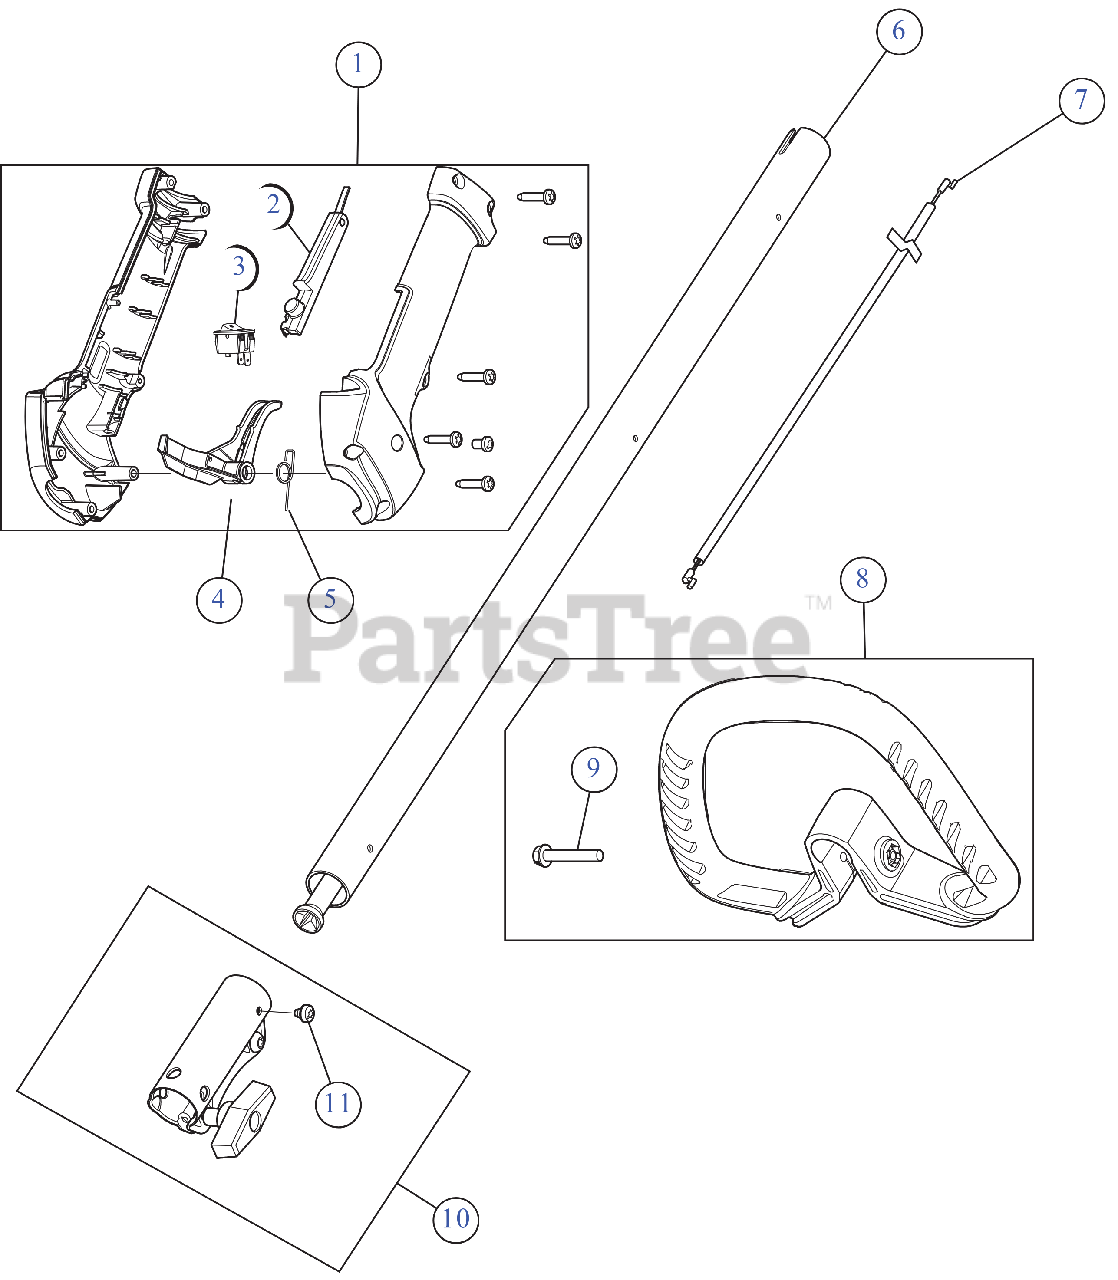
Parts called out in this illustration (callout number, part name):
1	THROTTLE GRIP ASSEMBLY
2	LEVER LOCK OUT
3	SW, MOMENTARY ON/O
4	THROTTLE TRIGGER
5	SPRING TRIG
6	BOOM ASSEMBLY UPR
7	THROTTLE CABLE
8	HANDLE ASSEMBLY
9	BOLT 1/4-20X1 1/2
10	SPLIT BOOM COUPLER KIT
11	SCREW, 10-32X.250 TA
